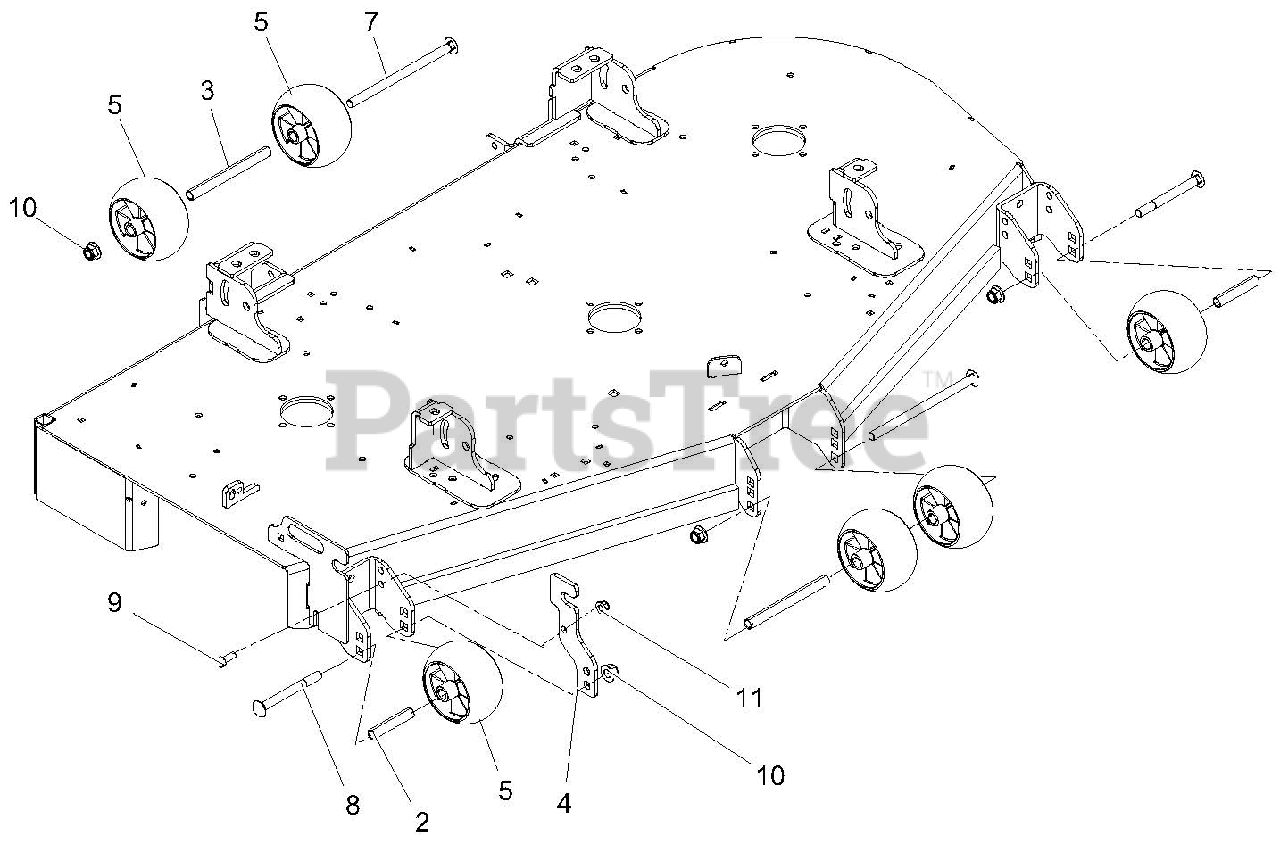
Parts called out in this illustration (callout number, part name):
2	SPACER, .510X.625X3.35
3	SPACER, .510X.625X6.70
4	CHUTE STORAGE BRACKET
5	ANTI-SCALP WHEEL - 5X3 CTR
7	BLT-RDHDSQNK .50-13X8.50
8	BLT-RDHDSQNK .50-13X5.00 G5
9	BLT-HEX .38-16X1.00 GR5 YWZC
10	NUT-LK-NYL-FLG .50-13 YWZC
11	NUT-LK-NYL-FLG .38-16 YWZC
